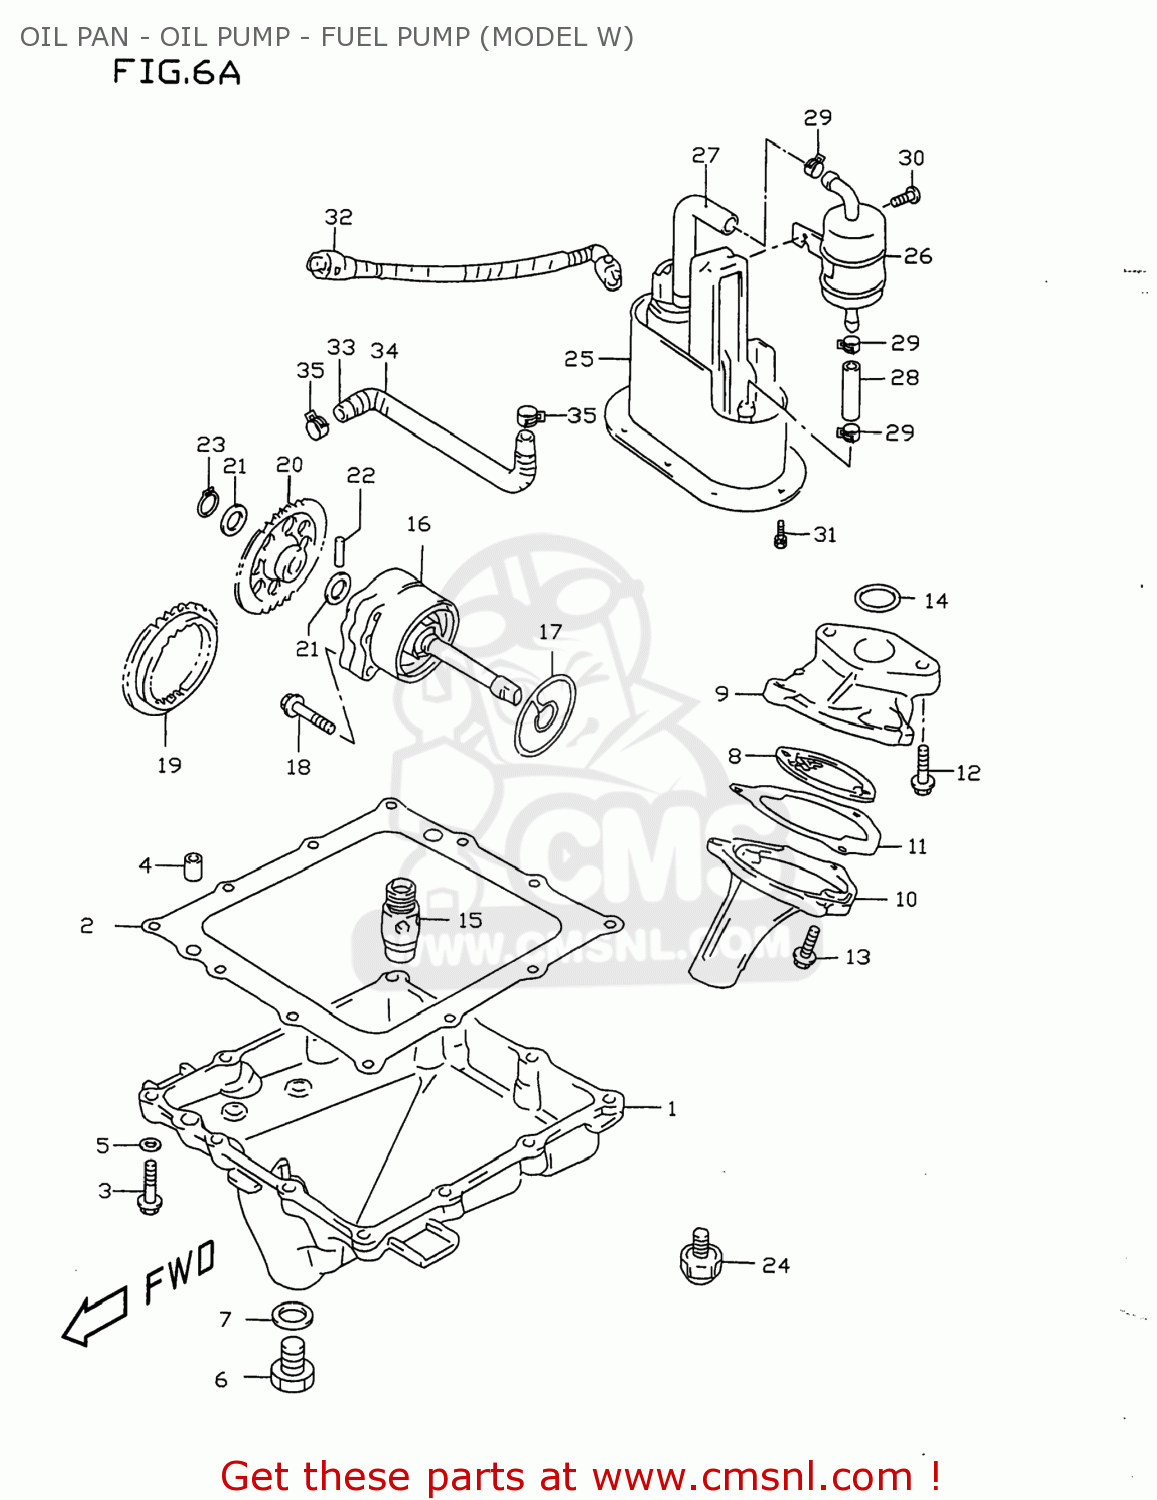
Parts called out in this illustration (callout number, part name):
1	PAN,OIL
2	GASKET,OIL PAN (NAS)
3	BOLT,G/S SWITC
4	PIN
5	GASKET(5.8X11X1.2) (NAS)
6	PLUG
7	GASKET(13.8X18.8X4.8) (NAS)
8	STRAINER,ENGINE OIL
9	PROTECTOR,OIL STRAINER
10	COVER,OIL STRAINER
11	GASKET,OIL STRAINER
12	BOLT
13	BOLT
14	O RING(D:2.62,ID:20.3)
15	VALVE ASSY,OIL RELIEF
16	PUMP ASSY,ENGINE OIL
17	O RING,OIL PUMP
18	BOLT
19	GEAR,OIL PUMP DRIVE (NT
20	GEAR,OIL PUMP DRIVEN
21	SHIM(12X20X0.5)
22	PIN(5X18)
23	CIRCLIP,12 MM
24	SWITCH ASSEMBLY,OIL PRESSURE
25	PUMP ASSEMBLY,FUEL
26	FILTER,FUEL
27	HOSE,FUEL
28	HOSE(7.6X14X600)
29	CLIP
30	SCREW
31	BOLT
32	HOSE,FUEL
33	HOSE(5.4X11.4X600)
34	(CA) SPRING
35	CLIP
